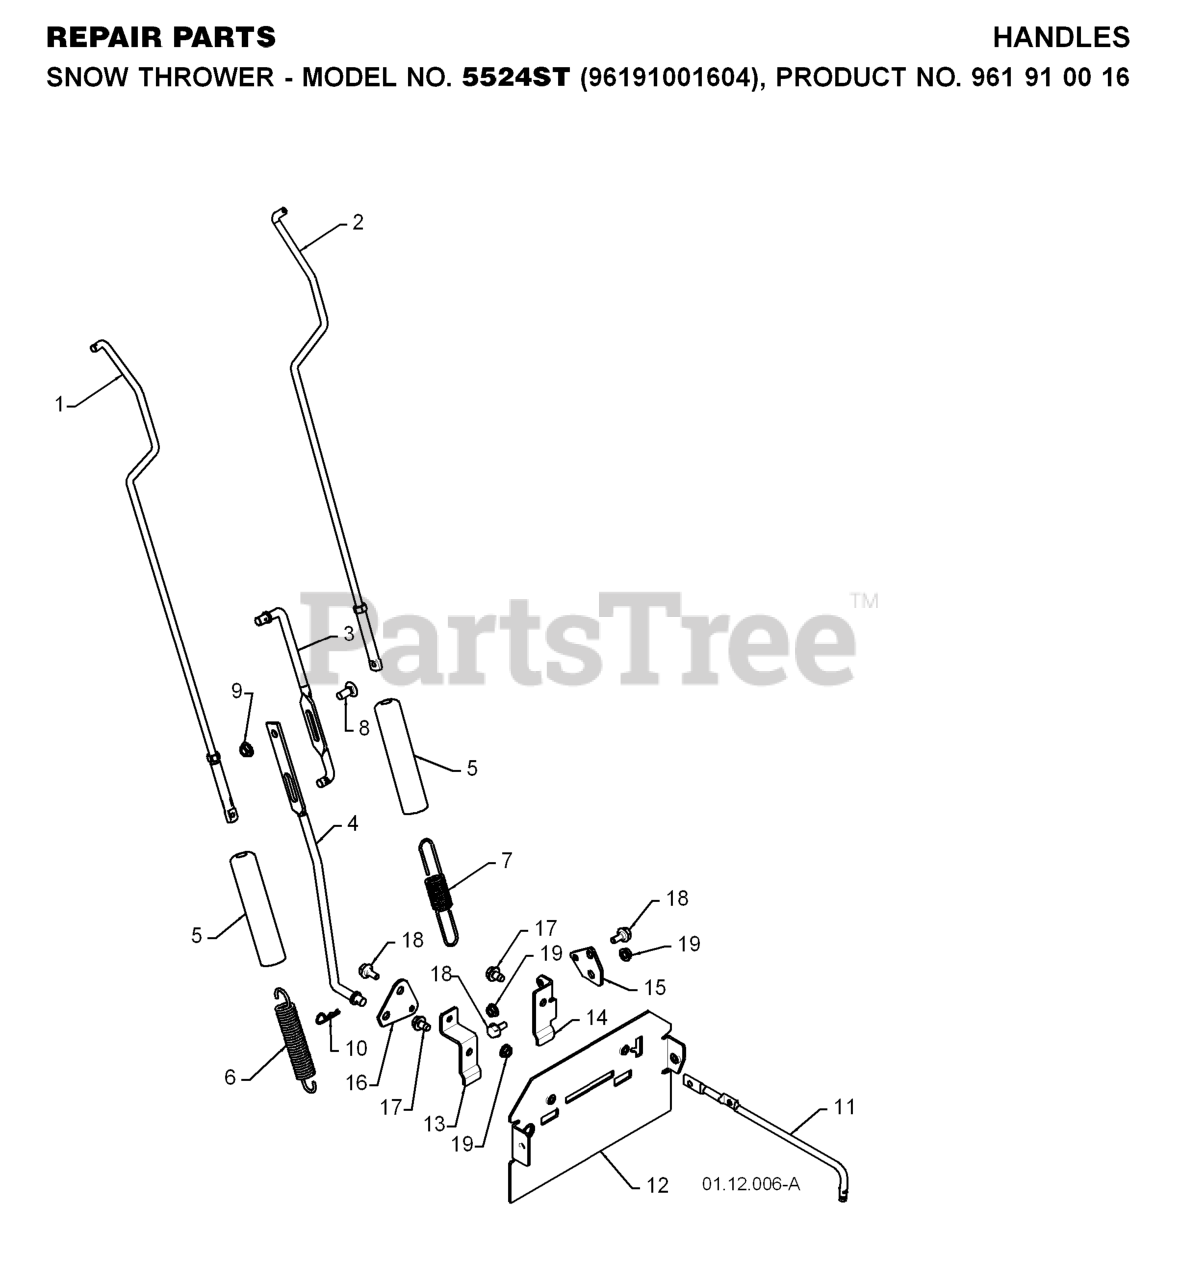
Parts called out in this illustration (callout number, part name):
1	ROD.ASM.IMPELLER
2	ROD.ASM.TRACTION
3	ROD, UPPER SPEED CONTROL
4	ROD, LOWER SPEED CONTROL.SNOW
5	SLEEVE, SPRING
6	SPRING, AUGER CONTROL
7	SPRING, TRACTION DRIVE
8	BOLT
9	NUT.FLANGE.5/16
10	SPRING RETAINER
11	ROD.CLUTCH.YELLOW.ZINC(VT)
12	PLATE.REAR.SNOW.PNT.ORANGE
13	BRACKET.SHIFTER.PLATE.BZP
14	BRACKET.CLUTCH.PLATE.BZP
15	PLATE.CLUTCH.BZP
16	PLATE.SHIFTER.BZP
17	Screw 5/16-18 x 1/2 Hex, Self Tapping 5/16-18 x 1/2
18	BOLT.SHOULDER.3/X.25
19	NUT.HEX.FLANGE.1/4
